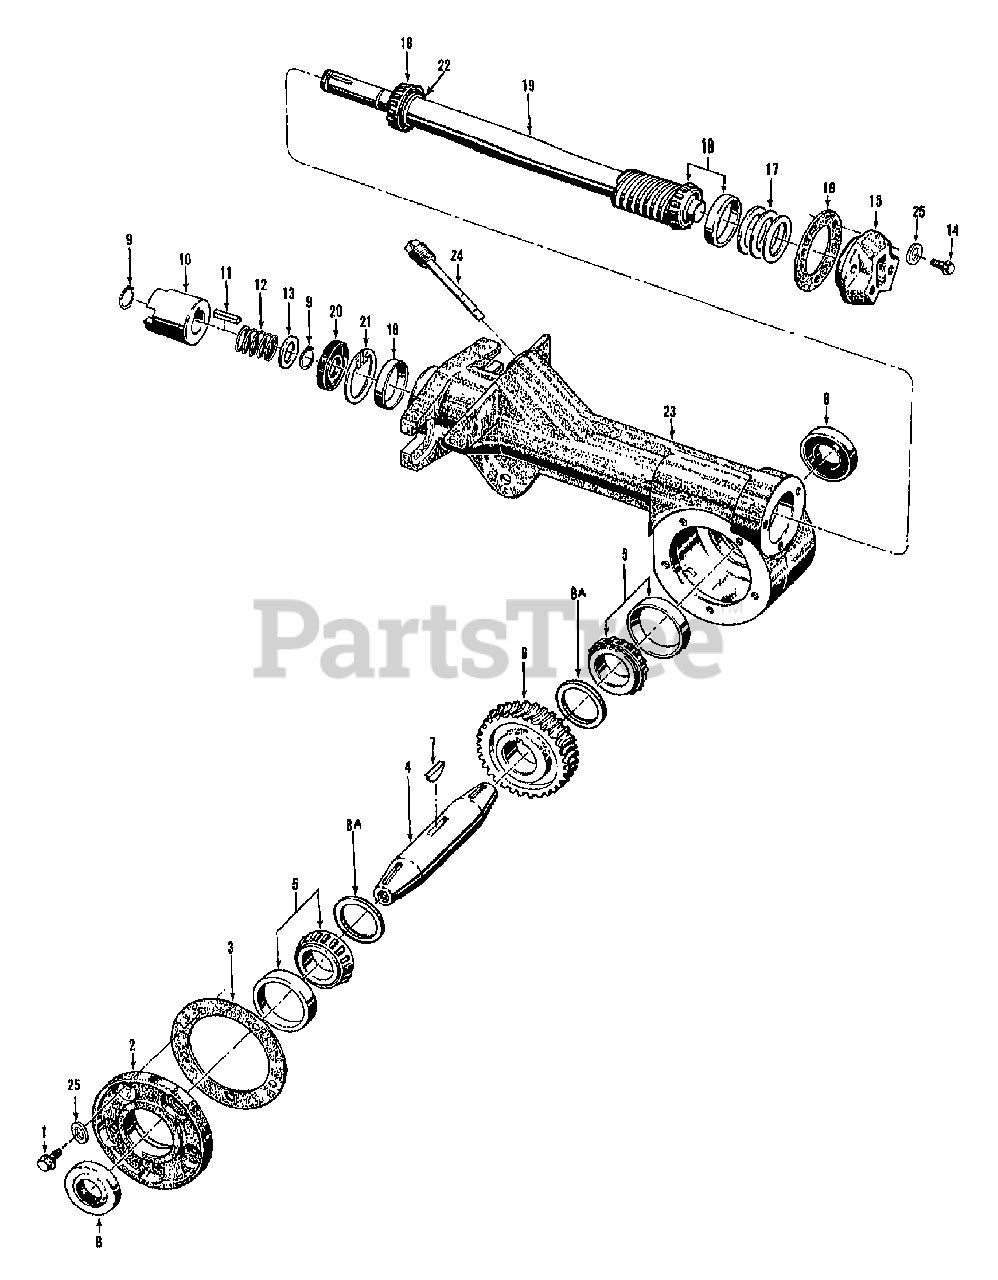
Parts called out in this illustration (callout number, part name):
1	SCR-HXSKT 1/4-20X.625
2	COVER-W/SCRS(TLR) (9780)
3	GASKET-TILLER COVER
4	SHAFT-TILLER
5	KIT-BEARING CUP & CONE
6	GEAR-WORM MACH
7	KEY-WOODRUFF .250X1.01
8	SEAL-OIL TILLERSHAFT
8A	WASHER-1.75X1.260X.054
9	RING-RETAIN EXT .707 ID
10	KIT-CLUTCH DOGS TILLER
11	KEY-.188 SQX1.0
12	SPRING (TC)
13	SHIM-1.0X.7656X.062
14	SCR-HFLK 1/4-20X.87
15	CAP-REAR #1115
16	GASKET-BRG COVER
17	SHIM-1.75X1.5X.01
17	SHIM-1.75X1.5X.03
17	SHIM-1.75X1.5X.005
17	SHIM-1.75X1.5X.062
18	KIT-BRG CONE&RACE-DRIVESHAFT
19	KIT-TILLER DR SHAFT (INCL. 18)
20	SEAL-OIL DRIVESHAFT
21	RING-RETAINING 5000-181
22	SHIM-1.0X.7656X.062
23	HSG-TLR ATT W/SLEEVE/RACEH3 (INCL. 5)
24	ASSM-OIL DIPSTICK
25	WASHER, NYLON 1/4". NOT REUSABLE.
